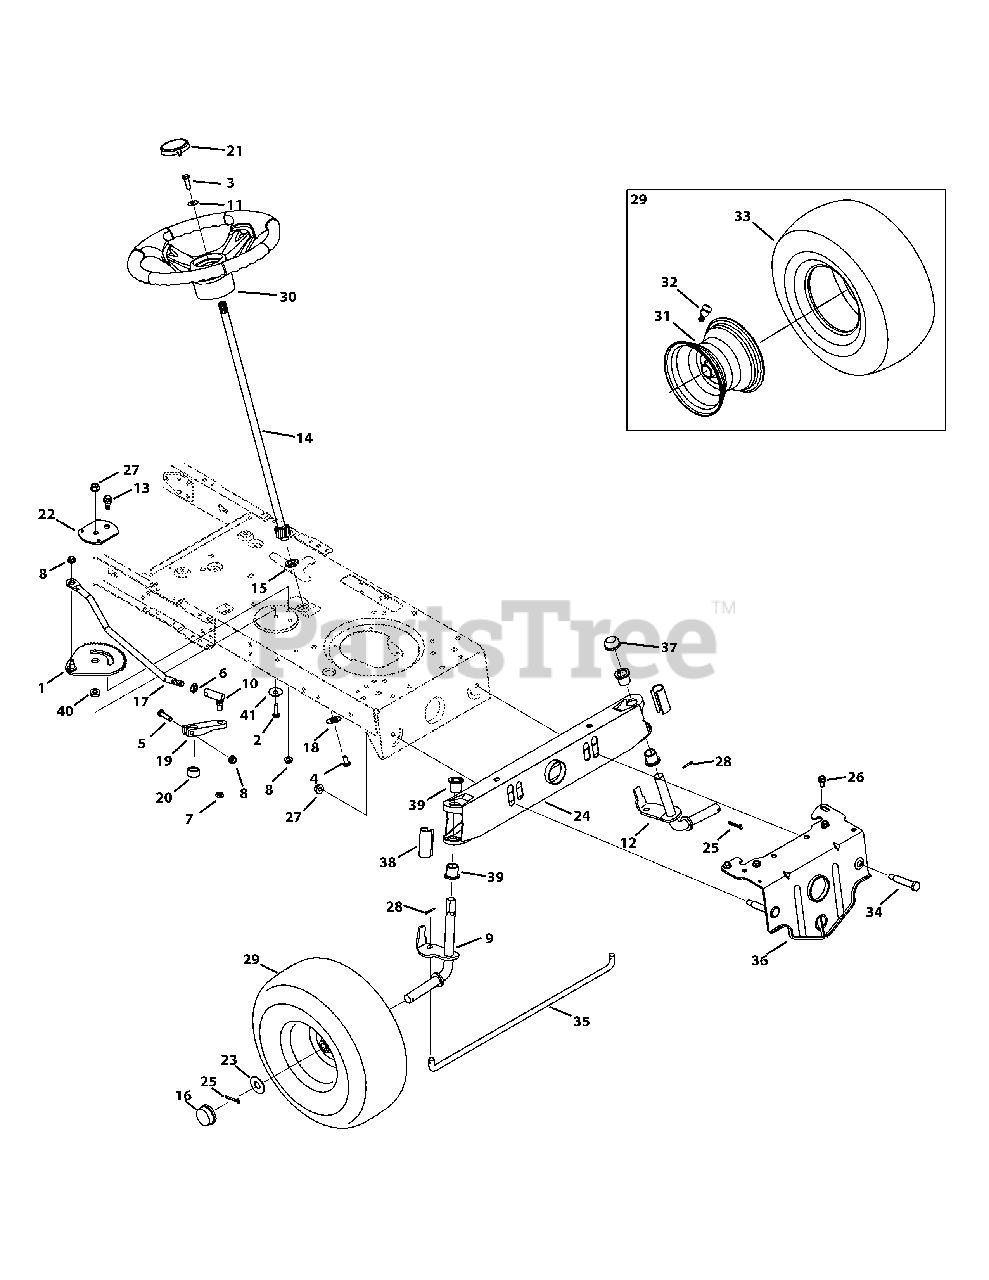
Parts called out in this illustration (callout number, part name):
1	Front Steering Gear Assembly
2	Hex Screw, 3/8-16 x 1.00
3	Hex Screw, 5/16-18 x 1.00, Lock
4	Machine Screw, 5/16-18 x .750
5	Hex Screw, 5/16-18 x 1.75
6	Jam Nut, 7/16-20
7	Jamlock Nut, 3/8-24
8	Flangelock Nut, 5/16-18
9	Front RH Axle
10	Ball Joint, 7/16-20
11	Bell Washer, .340 x .872 x .060
13	Shoulder Bolt, 5/16-18 x .435 x .350
14	Steering Shaft, 5/8
15	Flange Bearing, 5/8
17	Steering Link
18	Cap, 1.25 x .16
19	Steering Block
20	Spacer, .71 x .125 x .56
21	Cap, Troy-Bilt
22	Stabilizer Plate
23	Flat Washer, .781 x 1.590
24	Pivot Axle
25	Cotter Pin, 5/32 x 1.25
26	Screw, 5/16-18 x .750
27	Flangelock Nut, 3/8-16
28	Cotter Pin, .125 x .75
29	Wheel Assembly
30	Steering Wheel
31	Rim, 6.0 x 4.5
32	Valve, tubeless Air
33	Tire, 15 X 6 X 6 Rd Shldr
34	Shoulder Bolt, 3/8-16 x .500 x 2.38
36	Pivot Bar Bracket
37	Push Cap, 3/4
38	Standard Axle Cap
39	Flange Bearing, .760 x .941 x 1.0
40	Spacer, .38 ID x .854 OD x .20
41	Bell Washer, .390 x 1.13 x .062
